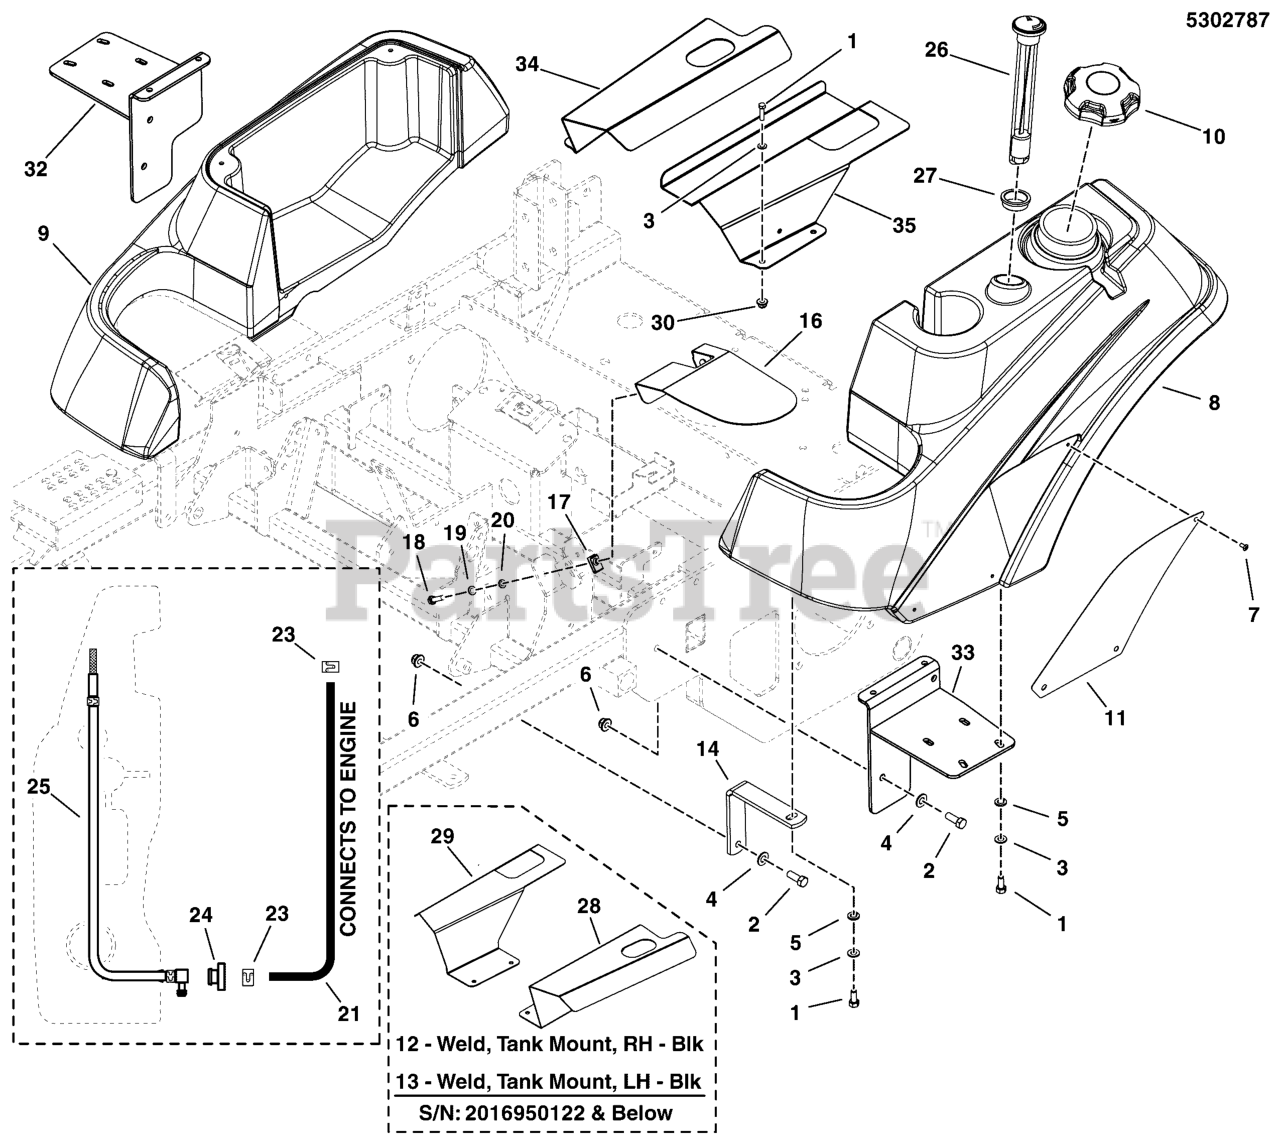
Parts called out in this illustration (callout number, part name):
1	BOLT, 5/16-18 X 3/4 GD5
2	BOLT, 3/8-16 X 1" GD5 CZ
3	WASHER, 5/16" SAE
4	WASHER, 3/8 SAE
5	WASHER, 5/16 LOCK CZ
6	NUT, 3/8-16 HEX NYLOCK FLANGE
7	SCREW, #10-24 X 3/8 ALLEN BHBZ
8	TANK, FUEL - LH, IS500 & IS1500
9	TANK, FENDER, CITATION/ZT4000 - RH
10	FUEL CAP, 3-1/2", MANAGED VENT OUT, 12"
11	BADGE, IS1500Z, RED
12	WELD, TANK MOUNT, RH - BLK
13	WELD, TANK MOUNT, LH - BLK
14	BAR, TANK MOUNT, FRONT - BLK
16	GUARD, MOTION CONTROLS, LH - BLK
17	BODY CLIP, 1/4-20 X 1/2 DEEP
18	BOLT, 1/4-20 X 1" GD5 CZ
19	WASHER, 1/4 SAE
20	WASHER, 1/4 LOCK
21	HOSE, 1/4" FUEL, 14.00"
23	CLAMP, HOSE, EXTERNAL, 1/2 - RED
24	BUSHING-FUEL TANK RED RUBBER
25	PICKUP TUBE ASM, FUEL TANK
26	GAUGE, FUEL, 12
27	GROMMET, FUEL GAUGE
28	GUARD, FUEL MOUNT, LH - BLK
29	GUARD, FUEL MOUNT, RH - BLK
30	NUT, 5/16-18 HEX NYLOCK FLANGE
32	WELD, TANK MOUNT, F200XT, RH - BLK
33	WELD, TANK MOUNT, F200XT, LH - BLK
34	GUARD, FUEL MOUNT, F200XT, RH - BLK
35	GUARD, FUEL MOUNT, F200XT, LH - BLK
